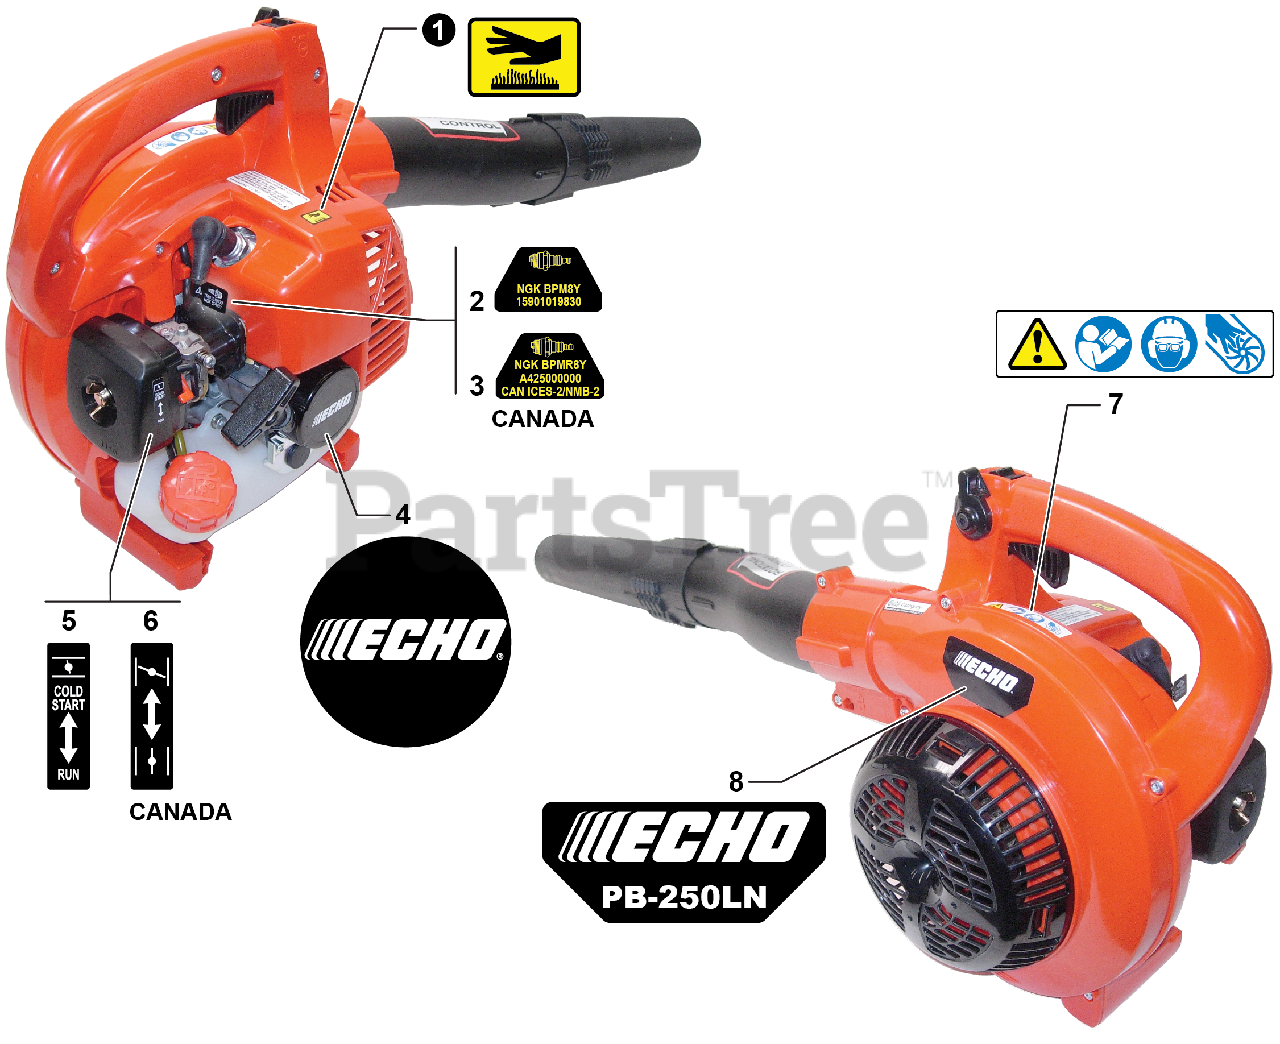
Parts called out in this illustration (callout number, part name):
1	LABEL, CAUTION - HOT
1	TUNE-UP KIT - YOUCANT
1	BULK PIPE - 3×5 MM BLACK (4 PIECES×2 M)
1	BULK STARTER ROPE - Ø 2.3 MM×61 M
2	LABEL, SPARK PLUG - BPM8Y
2	FILTER, AIR - DOUBLE LAYER
2	BULK PIPE - 3×6 MM BLACK (4 PIECES×2 M)
2	BULK STARTER ROPE - Ø 3.0 MM×61 M
3	LABEL, SPARK PLUG - BPMR8Y
3	FILTER, FUEL
3	BULK PIPE - 3×7 MM BLACK (4 PIECES×2 M)
3	BULK STARTER ROPE - Ø 3.5 MM×61 M
4	LABEL, RECOIL STARTER
4	SPARK PLUG - BPMR8Y
4	BULK PIPE - 3×6 MM CLEAR (4 PIECES×2 M)
4	BULK STARTER ROPE - Ø 4.0 MM×61 M
5	LABEL, CHOKE
5	FILTER KIT, AIR - YOUCANT
5	BULK PIPE - 2×4 MM CLEAR (4 PIECES×2 M)
5	BULK STARTER ROPE - Ø 4.4 MM×61 M
6	LABEL, CHOKE
6	BOLT, WING 5×20
6	BULK STARTER ROPE - Ø 4.8 MM×61 M
7	LABEL, CAUTION - ISO
7	COVER, AIR FILTER - BLACK
8	LABEL, ECHO PB-250LN
8	LABEL, CHOKE
9	FILTER, AIR - DOUBLE LAYER
10	FUEL SYSTEM KIT - YOUCANT
11	VENT ASSY
12	CLIP Ø6
13	PIPE, FUEL 3×5×80 BLACK
14	PIPE, FUEL 3×6×85 CLEAR
15	PIPE, FUEL 3×5×78 BLACK
16	GROMMET, FUEL Ø5
17	CONNECTOR, PIPE Ø5ר3.5
18	PIPE, FUEL 3×5×130 BLACK
19	FILTER, FUEL
20	GASKET, FUEL CAP
21	BULB, PURGE
